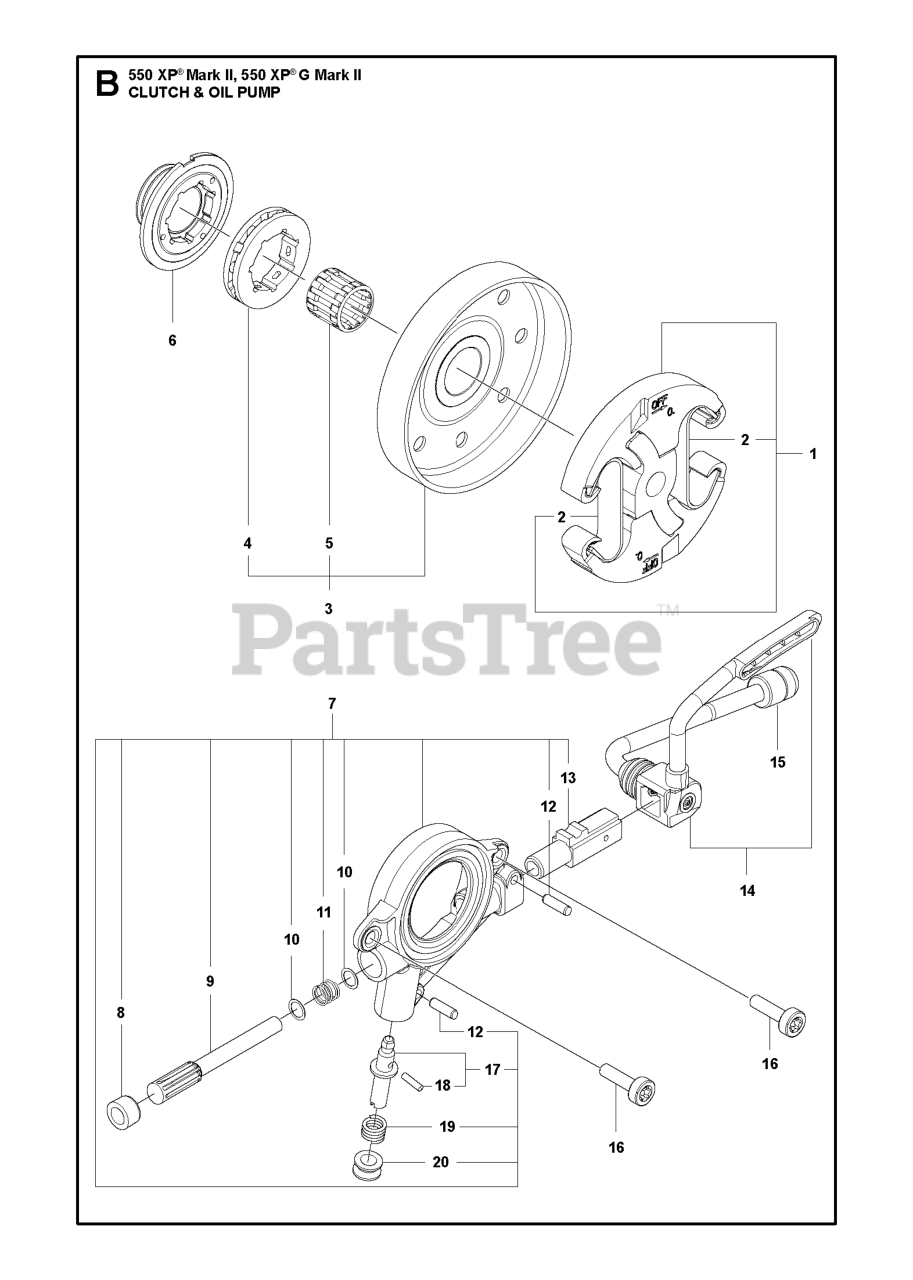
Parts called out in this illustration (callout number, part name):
1	CLUTCH ASSY
3	CLUTCH DRUM ASSY KIT SPARE PAR
4	RIM SPROCKET 7T .325
5	NEEDLE BEARING
6	WORM WHEEL 0,325
7	OIL PUMP ASSY 50CC_MARKII
9	PUMP PISTON 50CC
13	PUMP CYLINDER
15	OIL PLUMMET
16	SCREW ITXSCM M4X15 T27 12.9 T
17	ADJUSTING SCREW
